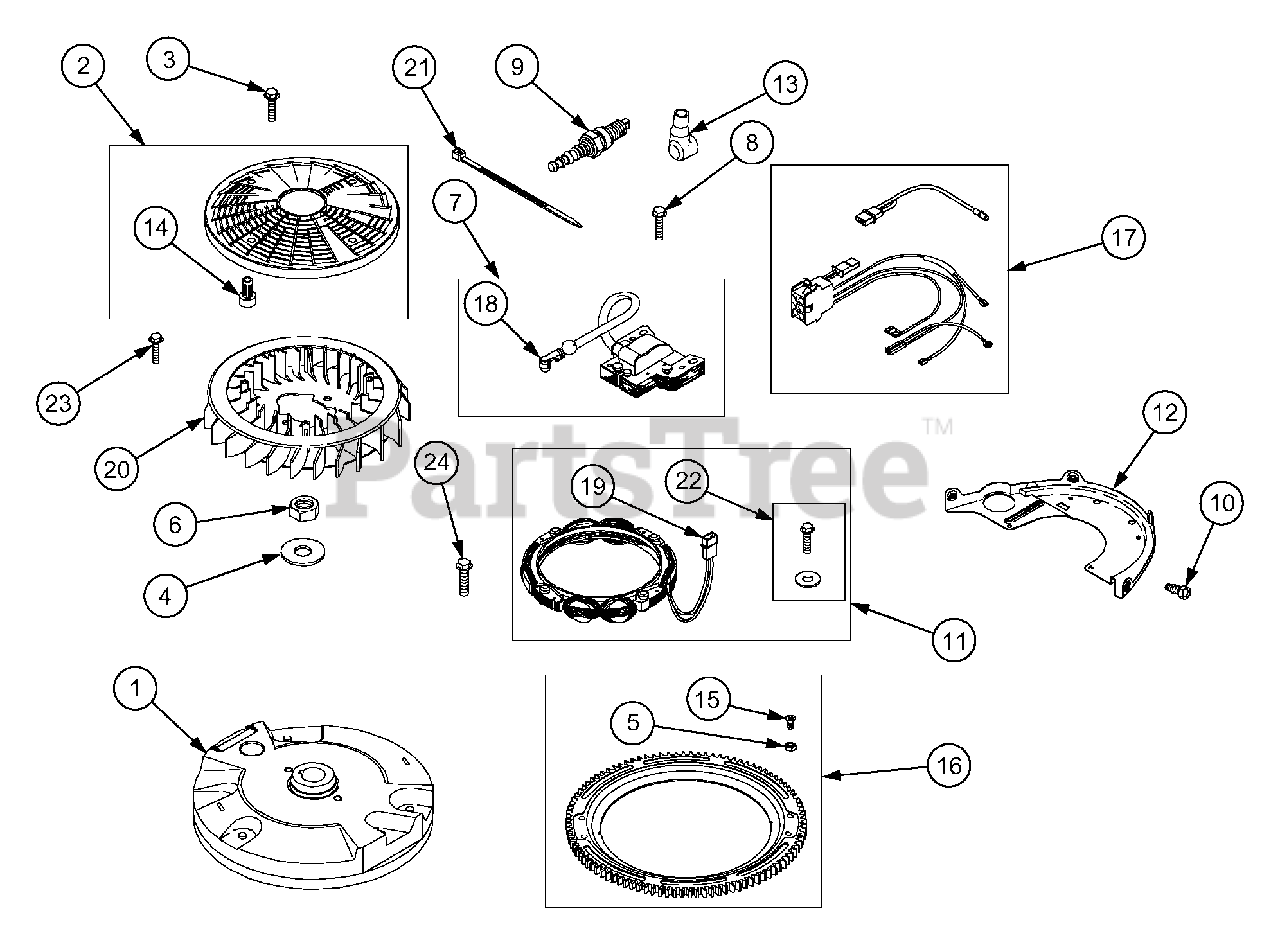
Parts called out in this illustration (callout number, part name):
1	Flywheel
2	Screen, Rotating
3	Screw (Rotating Screen)
6	Nut, Flywheel
7	Armature, Magneto
9	Spark Plug (RC12YC)
11	Alternator
12	Plate, Back
13	Boot, Spark Plug
16	Gear, Ring
17	Harness, Wiring
18	Terminal, Spark Plug
19	Wire/Connector, Alternator
20	Fan, Flywheel
21	Tie, Cable
22	Kit, Screw/Washer
23	Screw
24	Screw
